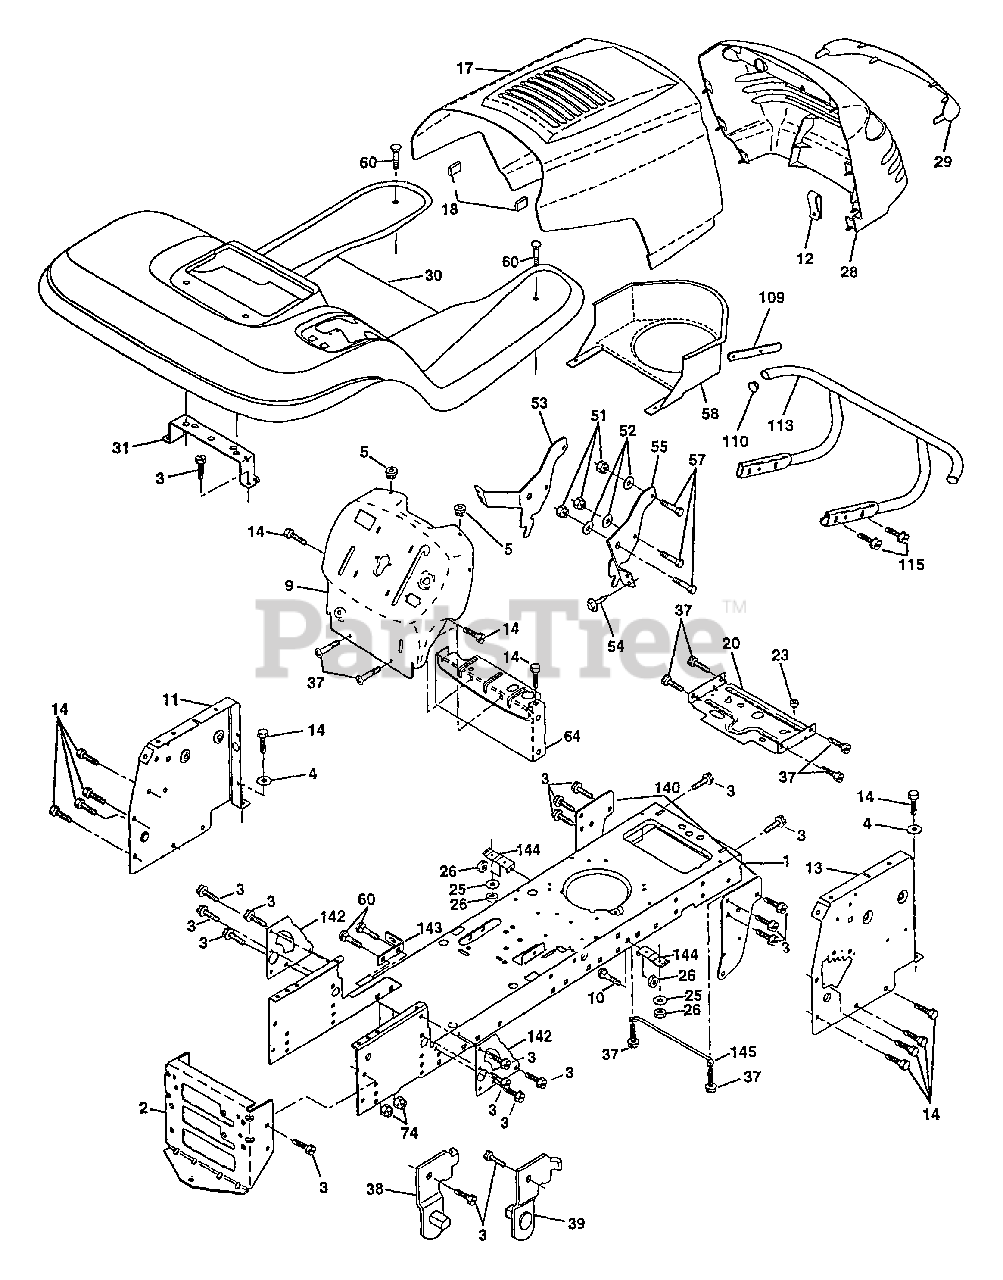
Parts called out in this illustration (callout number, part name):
1	Chassis
2	Drawbar, Stretch (AYP part number)
3	Screw Thdrol 3/8-16x3/4 Ty-tt
4	Washer 13/32 x 3/4 x 16 Ga.
5	Bumper Hood/Dash
9	Dash P/L E A Hm NC Sym
10	Bolt Carriage 3/8-16 x 1 (AYP part number)
11	Panel Dash Rh (AYP part number)
12	Clip Tinnerman
13	Panel Dash Rh
14	Screw Thdrol 3/8-16x1/2 Ty-tt
17	Hood PNT STL P/L
18	Bumper Hood
20	Plate Mtg Battery Fuel Tank Fr (AYP part number)
23	Bushing (AYP part number)
25	Washer 13/32 X 13/16 X 12 Ga
26	Nut Lock Hex W/Ins 3/8-16 Unc
28	Grille LT/PL
29	Lens LT/PL (AYP part number)
30	Fender Footrest STLT Pnt
31	Bracket Support Fender
37	Screw Thdrol 6/16-18 x 1/2 TYT
38	Bracket, Asm. Pivot, L.H., Mower Rear
39	Bracket, Asm, Pivot, R,H., Mower Rear
51	Nut Lock Hex W/Ins 1/4-20
52	Washer 9/32 x 7/8 x 16 Ga.
53	Bracket Grille Lh
54	Screw Hex Wshd 8-18 x 7/8
55	Bracket Grille Rh
57	Bolt Hex 1/4-20 x 3/4 (AYP part number)
58	Air Duct Engine
60	Bolt Rdhd Sqnk 3/8-16unc x 3/4
64	Dash Lower STLT
74	Nut Crownlock 3/8-16 UNC
109	Bracket Extension Bumper (AYP part number)
110	Plug Plastic
113	Bumper Asm
115	Screw Thdrol 3/8-16 x 1-1/4
140	Bracket Suspension Front
142	Plate Reinforcement STLT (AYP part number)
143	Bracket Swaybar Chassis (AYP part number)
144	Bracket Pnt Footrest STLT (AYP part number)
145	Rod Pivot Chassis/Hood
